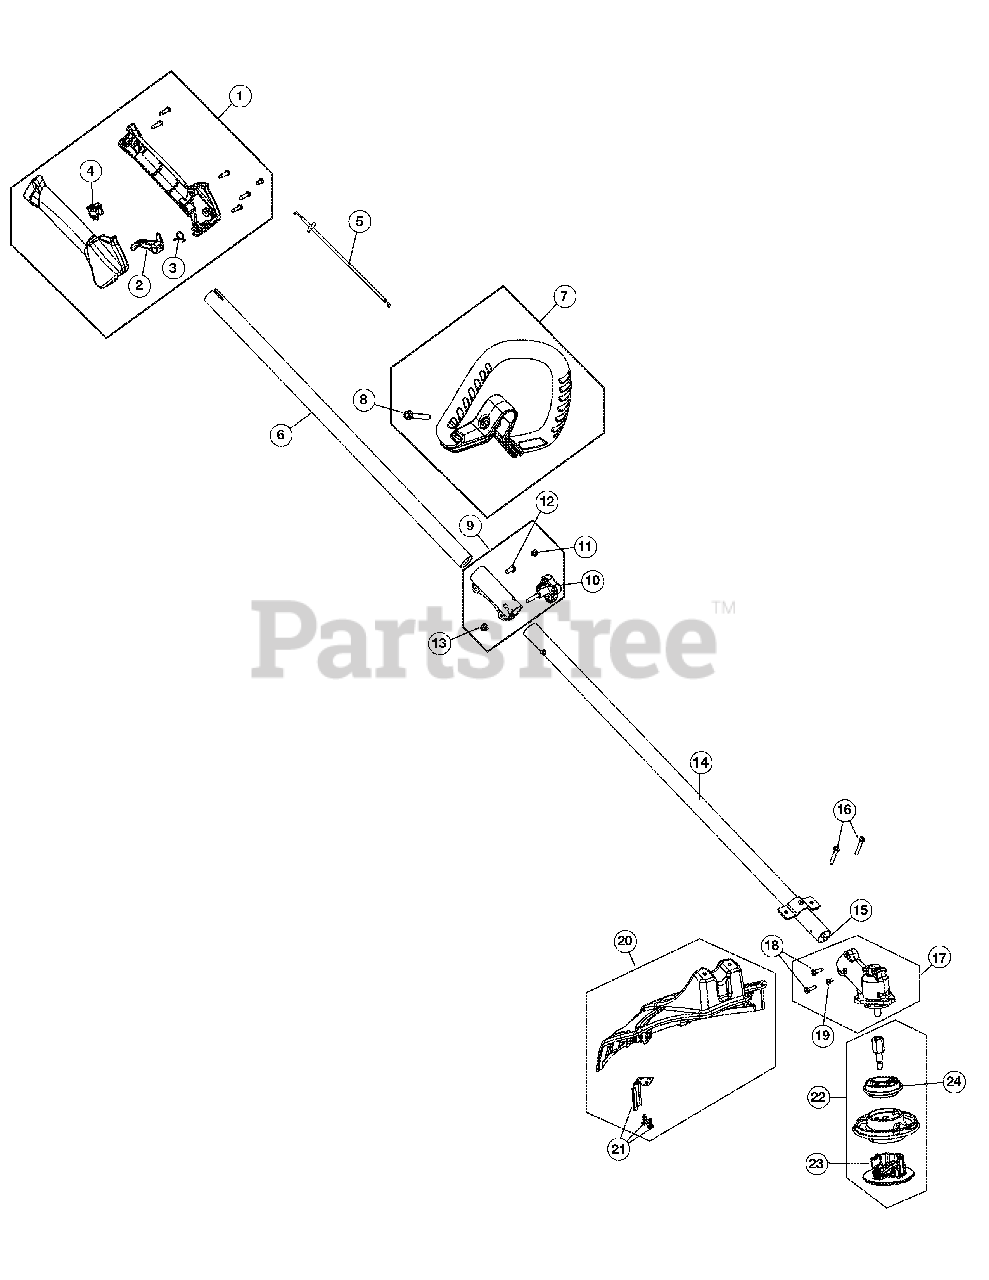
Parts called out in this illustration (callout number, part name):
1	Throttle Housing Assembly
2	Throttle Trigger
3	Throttle Trigger Spring
4	Switch Assembly
5	Throttle Cable Assembly
6	Upper Drive Shaft Assembly
7	D-Handle Assembly
9	Split Boom Coupler
10	Adjustment Knob
11	Coupler Anti-Rotation Screw
12	Coupler Bolt
13	Adjustment Knob Nut
14	Lower Drive Shaft Housing
15	Lower Flexible Drive Shaft
16	Shield Mount Screw Assembly
17	Gearbox Assembly
18	Gearbox Screw
19	Gearbox Anti-Rotation Screw
20	Shield Assembly
21	Blade Assembly
22	Cutting Head Assembly
23	Cutting Head Cap
